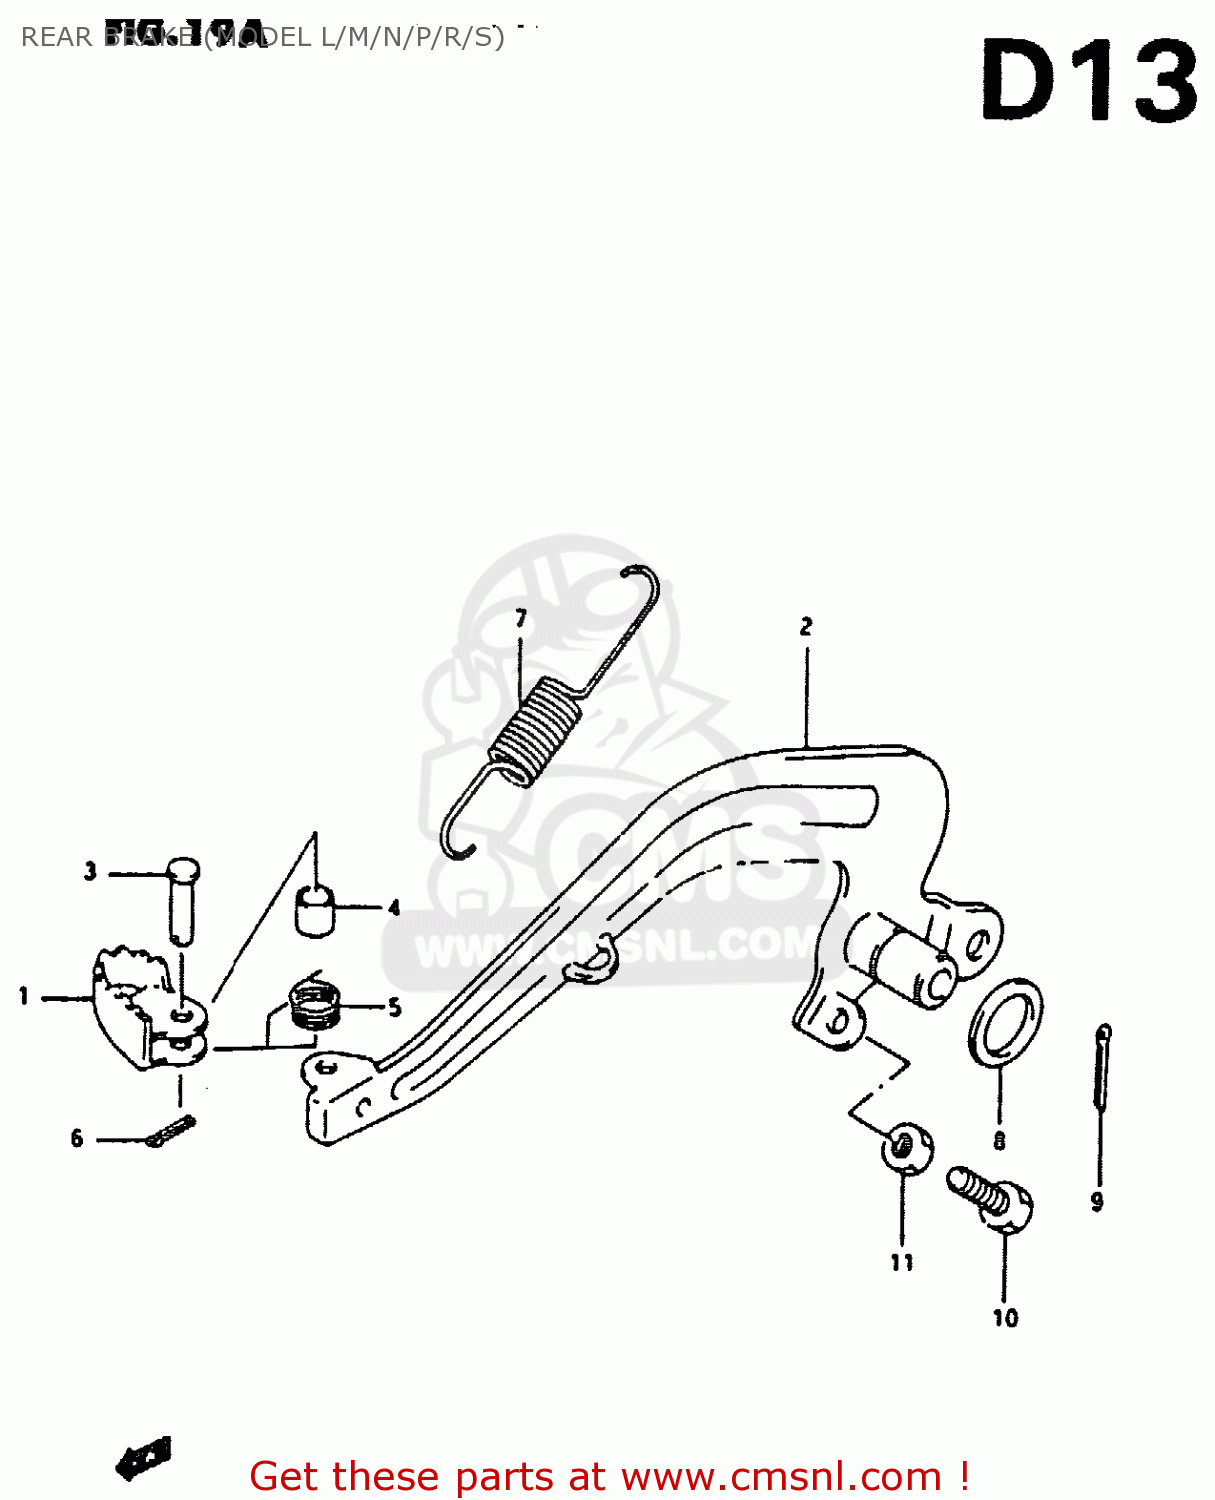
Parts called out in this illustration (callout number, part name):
1	PEDAL,BRAKE
2	ARM,BRAKE PEDAL
3	PIN
4	SPACER(9.2X9X6.5)
5	SPRING
6	PIN
7	SPRING
7A	SPACER
8	WASHER(15.5X26X2.3)
9	COTTER PIN
10	SCREW(6X23)
11	NUT 6MM
12	ROD ASSY,RR BRAKE
13	WASHER
14	SPRING
15	PIN(11X18)
16	NUT (6MM)
17	PIN
18	WASHER
19	PIN 20X20
